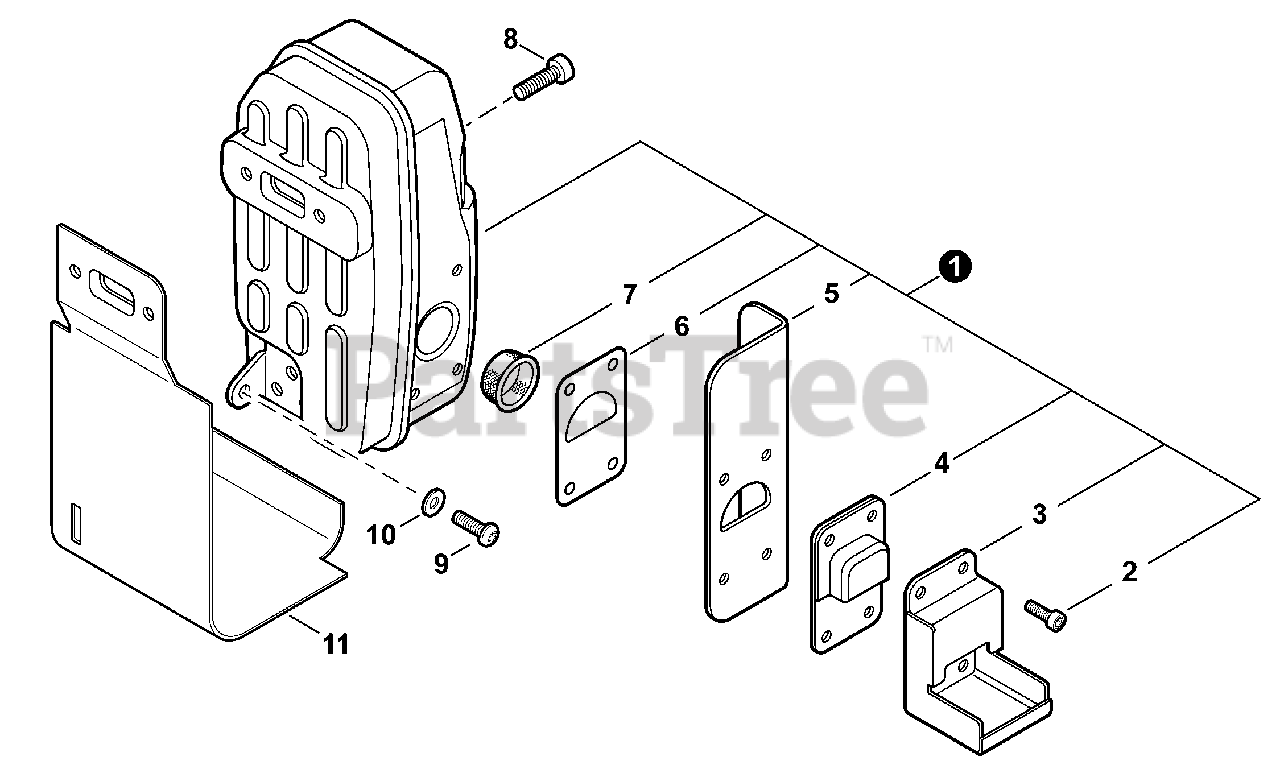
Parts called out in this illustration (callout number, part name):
1	MUFFLER ASSY
2	BOLT, TORX 4×12
3	GUIDE, EXHAUST
4	GUIDE, EXHAUST
5	HEAT SHIELD, EXHAUST
6	GASKET, EXHAUST
7	SCREEN, SPARK ARRESTER
8	BOLT, TORX 6×20
9	BOLT, TORX 5×16
10	WASHER 5.5×16×2T
11	HEAT SHIELD, EXHAUST
